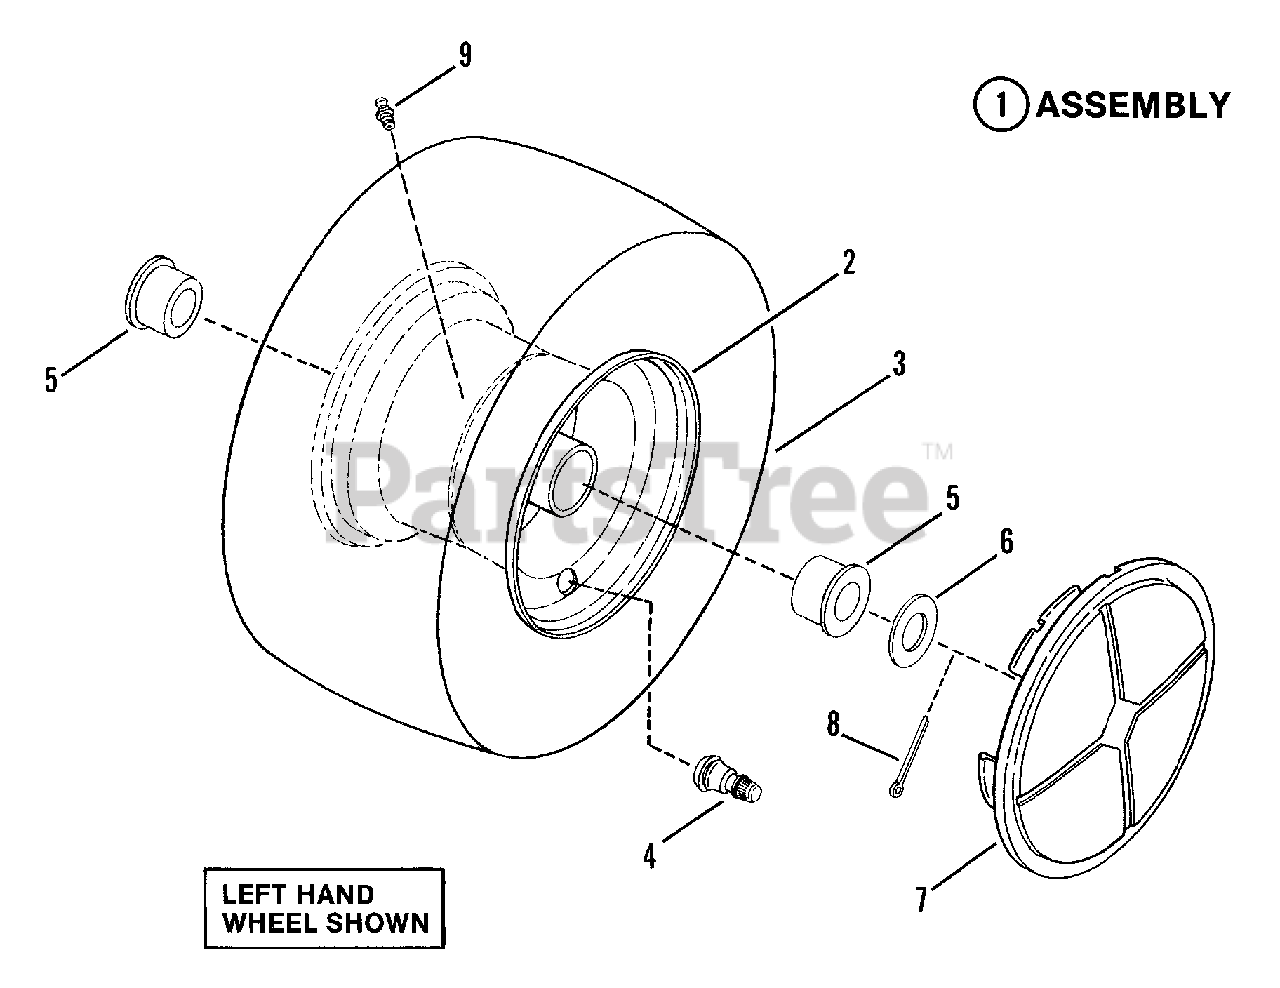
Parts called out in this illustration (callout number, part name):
1	ASSEMBLY, Front tire & Rim
2	RIM, 6 x 4.50
3	TIRE, 15 x 6.00 x 6
4	VALVE, Air
5	BEARING, Wheel
6	WASHER
7	WHEEL COVER
8	COTTER-PIN
9	FITTING, Lube 1/4-28 Tapered Thread
